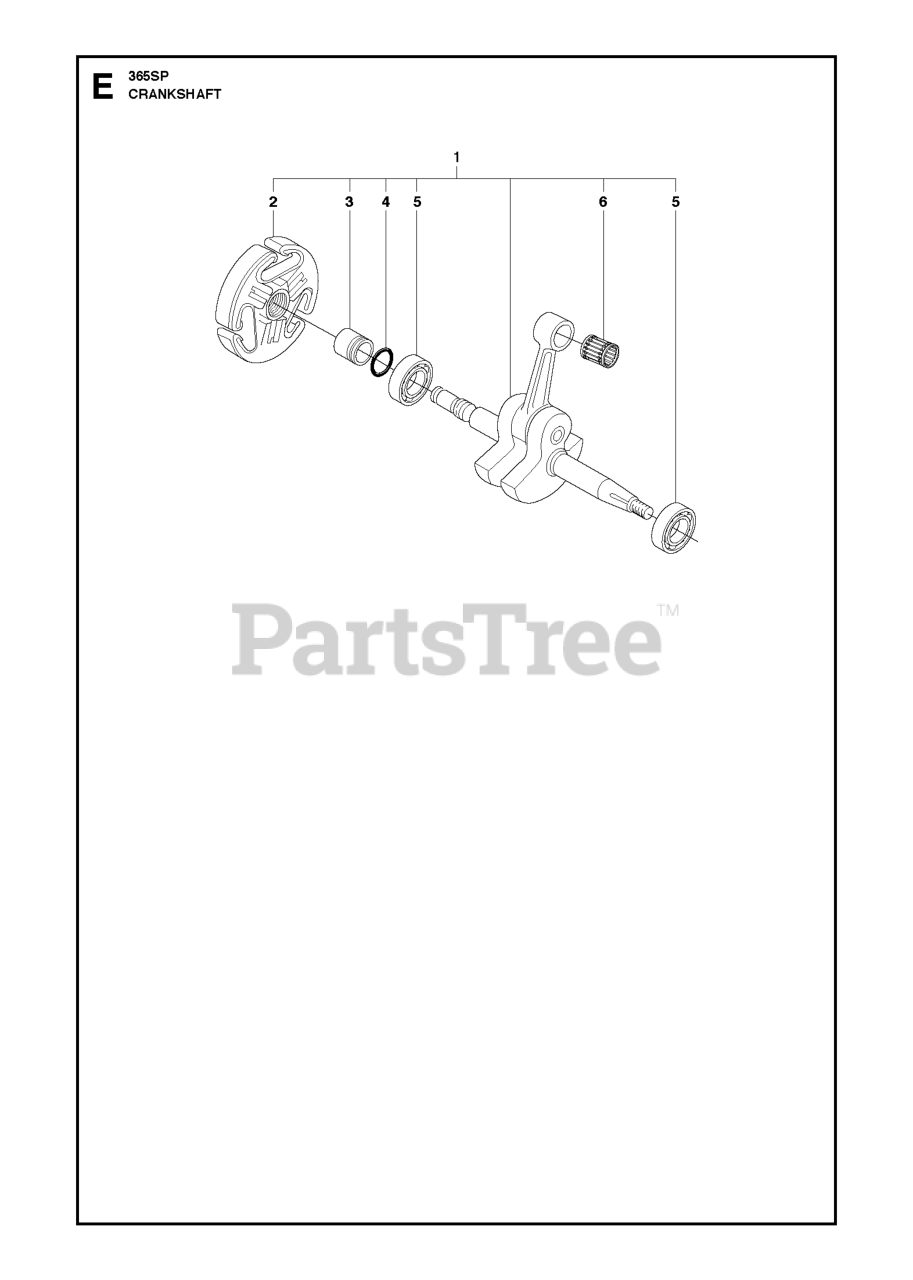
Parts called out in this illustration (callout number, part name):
1	CRANKSHAFT
2	CLUTCH ASSY M14X1.25-6H
5	BALL BEARING
6	NEEDLE BEARING PISTON PIN 12X1
